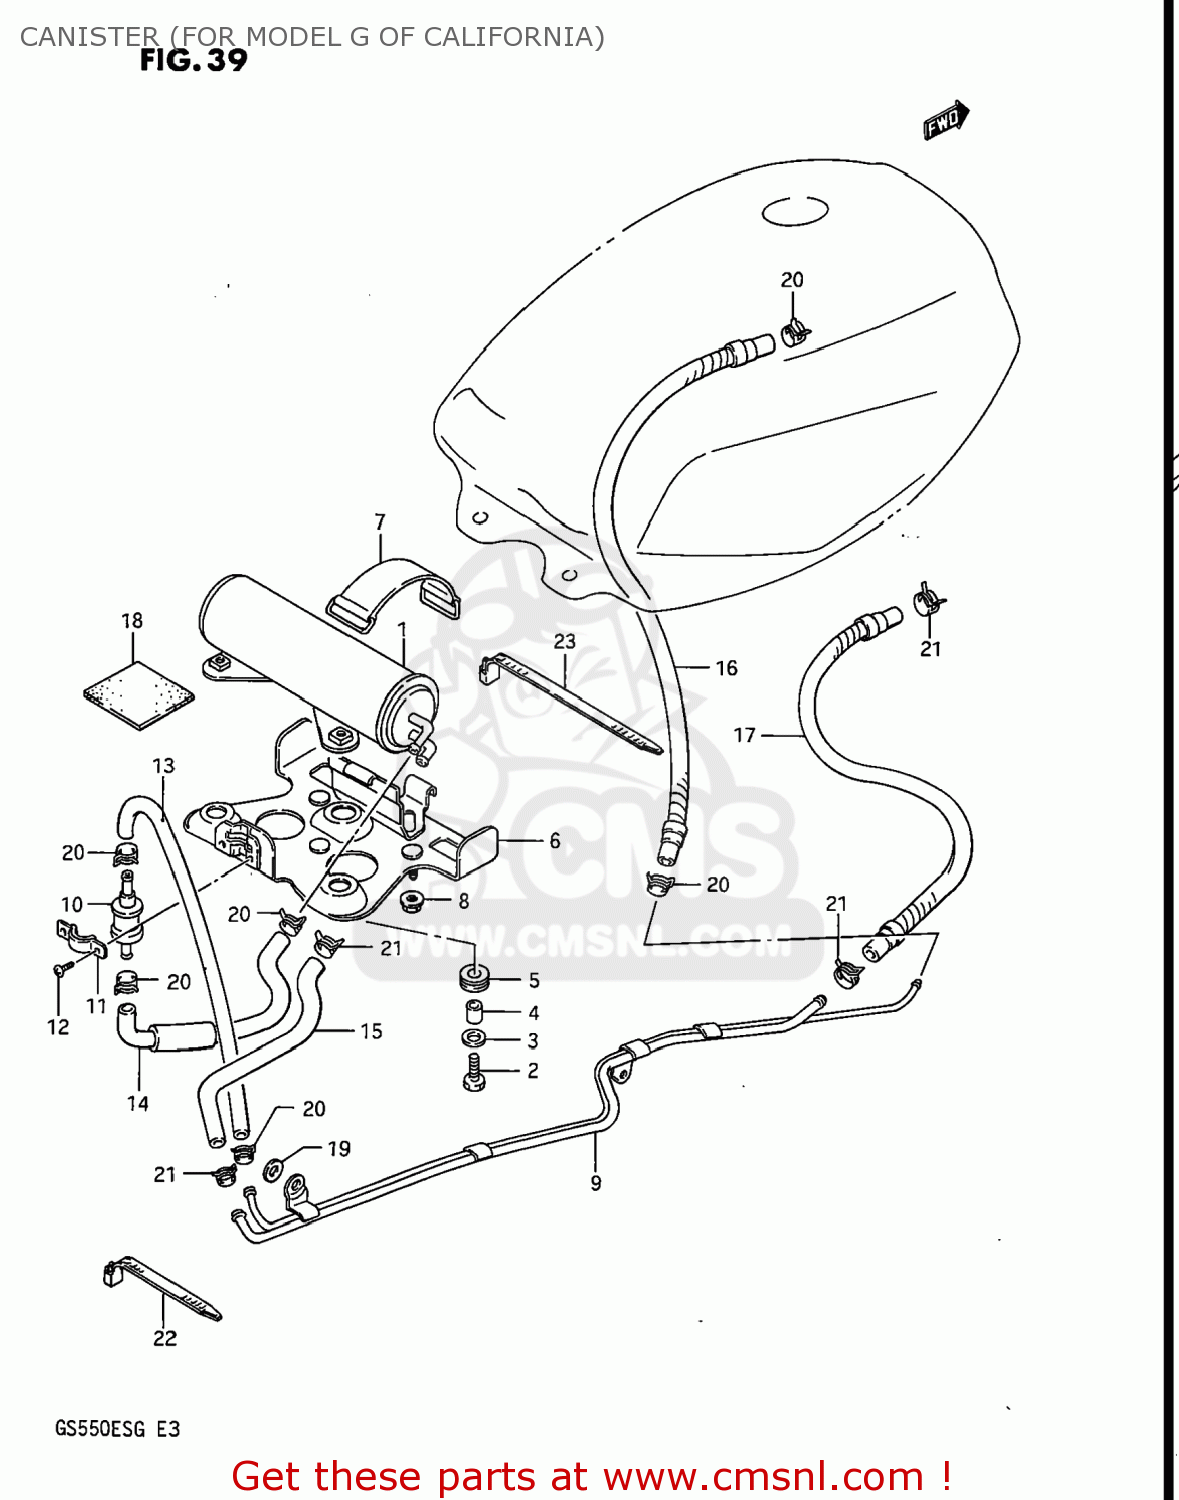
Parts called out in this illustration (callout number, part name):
1	(CA) CANISTER ASSEMBLY,CHARCOAL
2	BOLT
3	WASHER (6.5X18X1.6)
4	SPACER(6.1X9X7.5)
5	CUSHION
7	BAND
8	NUT
10	VALVE,FUEL TANK BREATHER
11	PLATE,FUEL TANK BREATHER NO.2
12	SCREW
16	(CA) HOSE,JOINT
17	(CA) HOSE JOINT
19	WASHER (8.5X16X2.6)
20	(CA) CLIP
21	CLAMP
22	CLAMP(L:95)
23	CLAMP(L:165)
